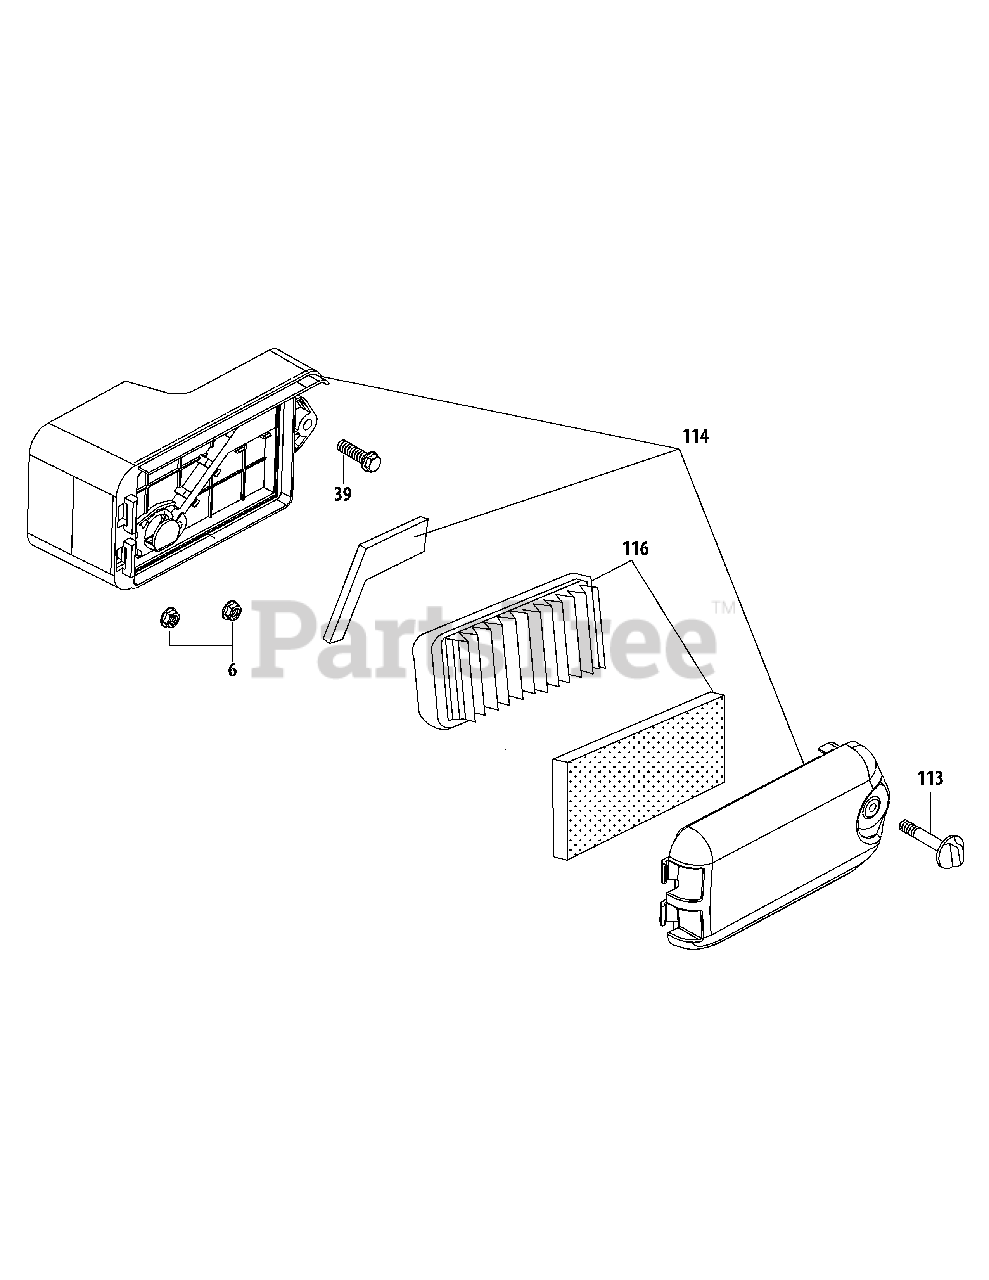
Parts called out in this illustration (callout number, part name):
6	Nut M6X10Mm
39	Bolt M6X35
113	Air Filter Cover Thumb Screw
114	Air Filter Cover
116	Air Filter Elements, Paper
